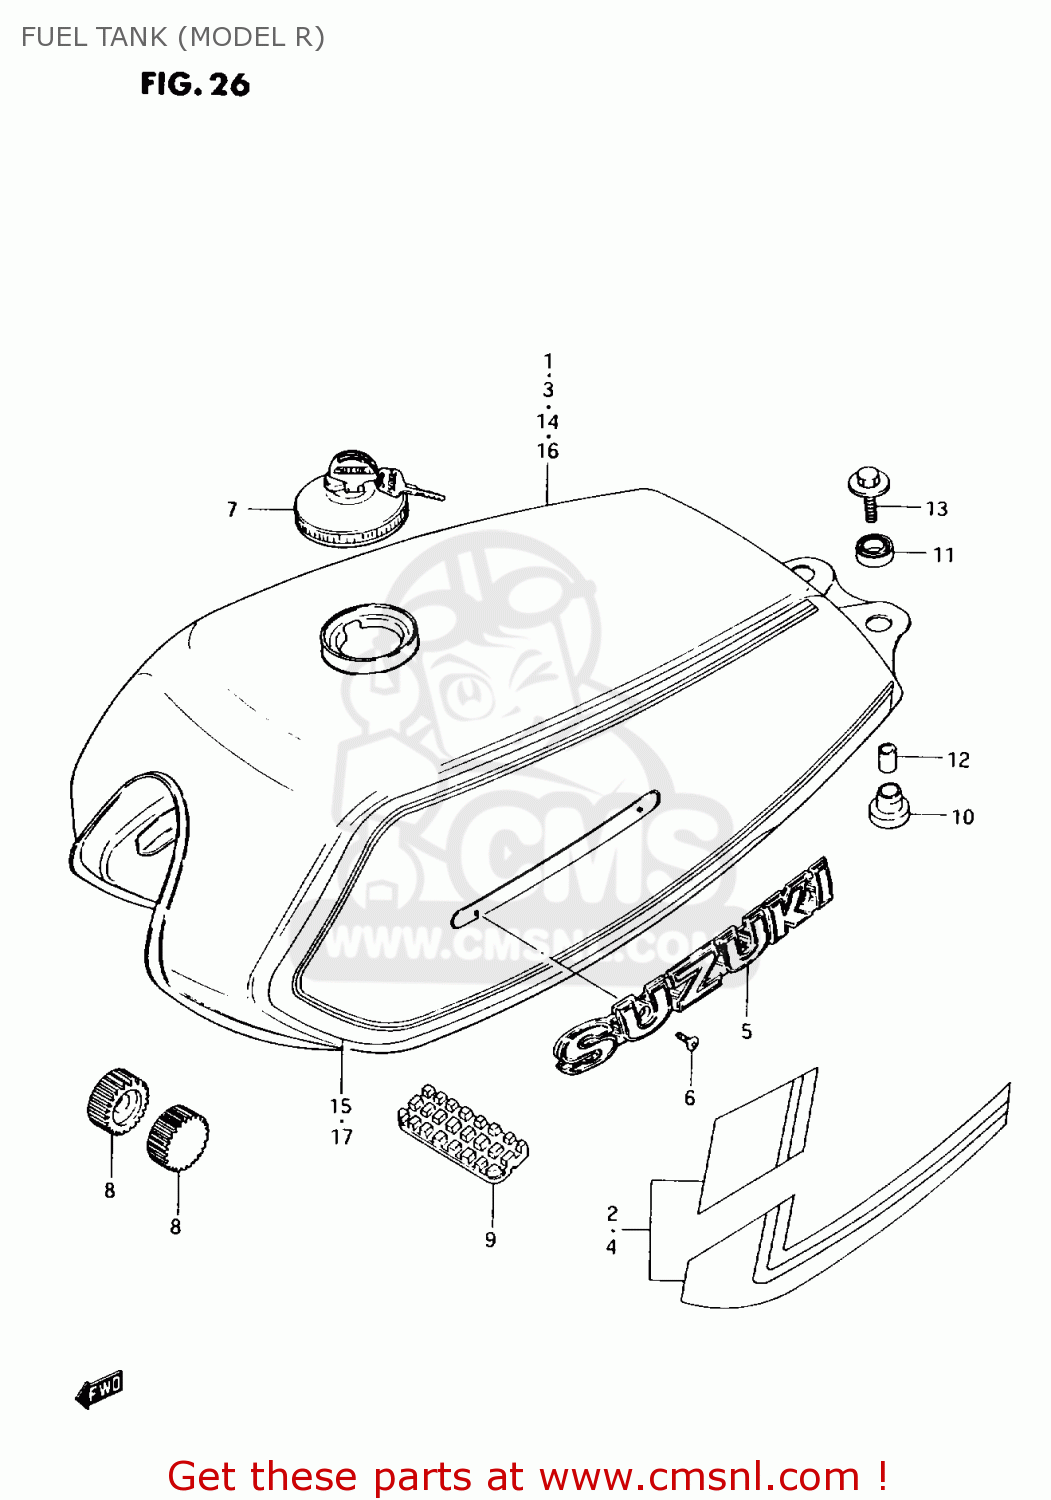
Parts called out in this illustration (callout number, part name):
1	TANK ASSY, FUEL (BLUE)
2	TAPE SET, FUEL TANK
3	TANK ASSY, FUEL (RED)
4	TAPE SET, FUEL TANK
5	EMBLEM,FUEL TANK
6	SCREW
7	CAP SET,FUEL TANK
8	CUSHION
9	CUSHION
10	CUSHION
11	CUSHION
12	SPACER(6.5X9X18)
13	BOLT(6X30)
14	TANK ASSY, FUEL (BLUE)
15	TAPE SET, FUEL TANK
16	TANK ASSY, FUEL (RED)
17	TAPE SET, FUEL TANK
